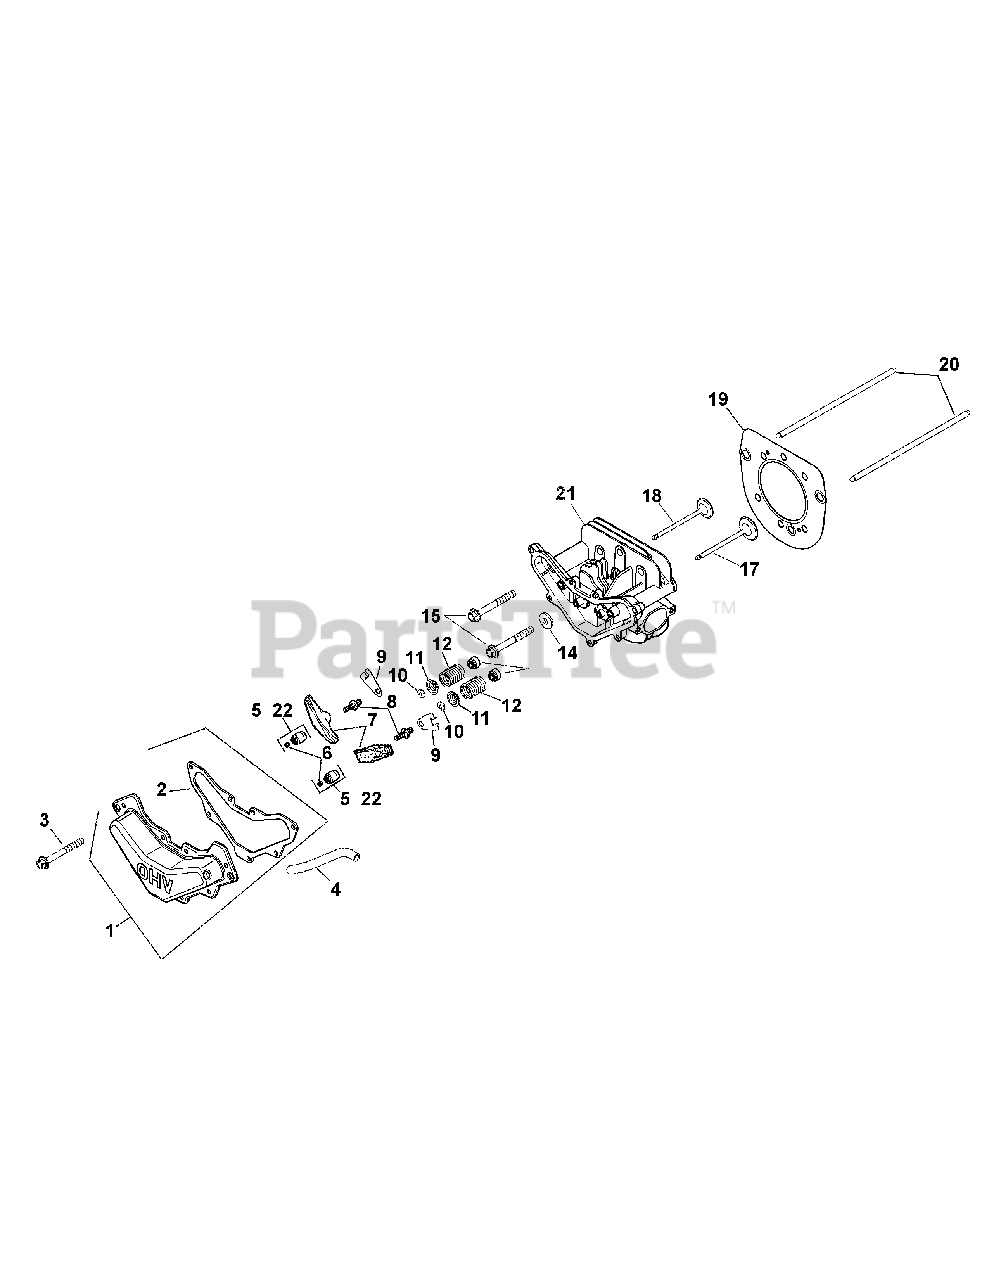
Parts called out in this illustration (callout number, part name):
1	Valve Cover Kit
2	Valve Cover Gasket
3	Flg. Thd. Frm. Screw, M6 X 1.0 X 20
4	Breather Hose
5	Rocker Pivot Assembly
9	Push Rod Guide Plate
10	Retainer Lock
11	Valve Spring Cap
14	Flat Washer, 13.32
15	Flange Screw, M10 X 1.5 X 80
16	Fuse Block
17	Exhaust Valve
19	Cylinder Head Gasket Kit
20	Push Rod
21	Cylinder Head Kit
22	Rocker Arm Pivot Kit
